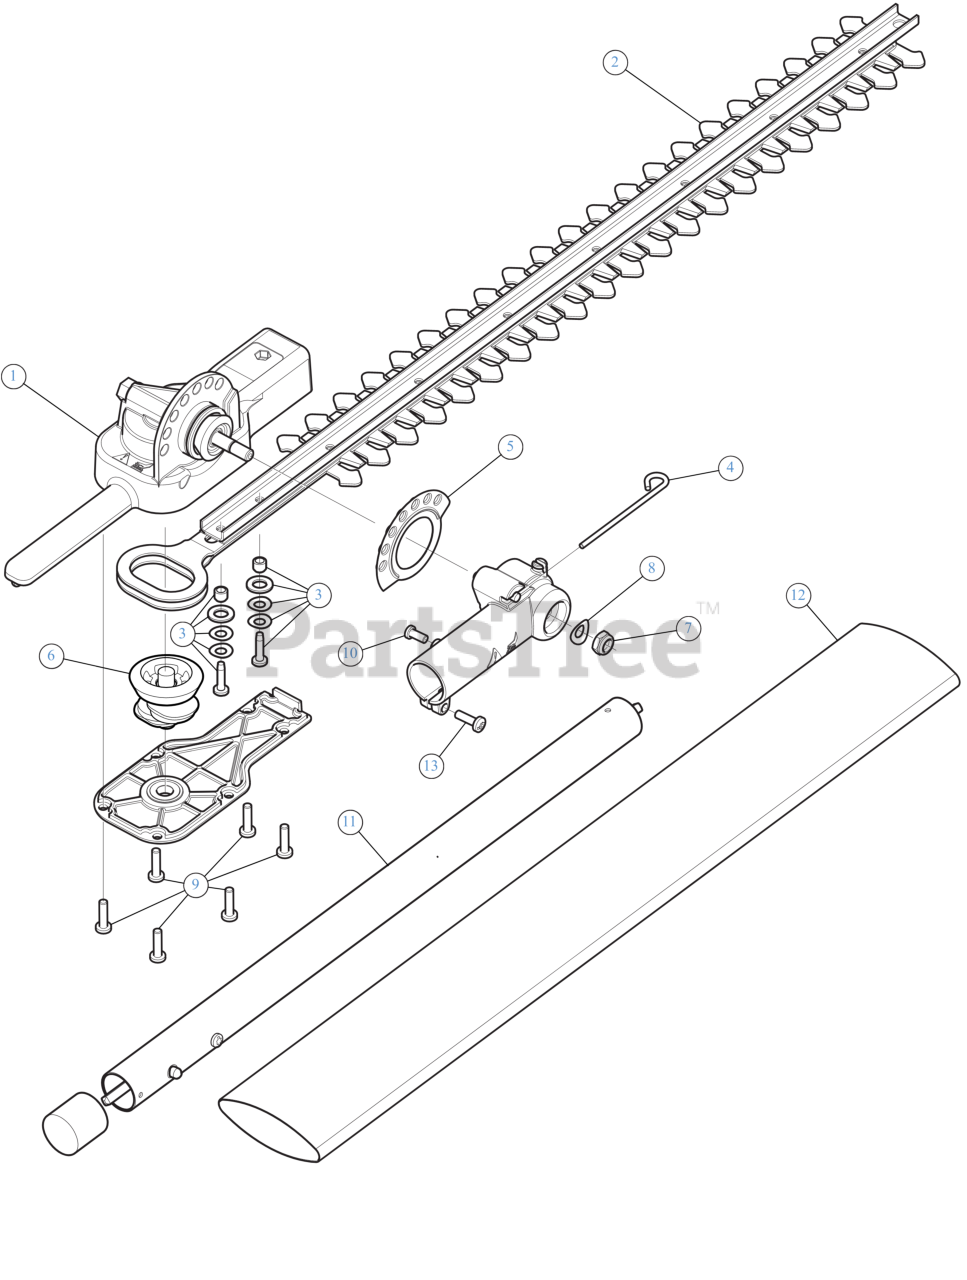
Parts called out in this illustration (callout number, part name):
1	GEARBOX ASSEMBLY
2	BLADE ASSEMBLY
3	BLADE HARDWARE
4	LOCKING LEVER PIN
5	SPACER DETENT SHM
7	NUT 5/16-24
8	SHAKE PROOF WASHER
9	SCREW - 10-24X.625 PAN HEAD
10	SCREW 8-32X.437
11	BOOM ASSEMBLY
12	BLADE COVER
13	SCR, M5 x 15.8MM
